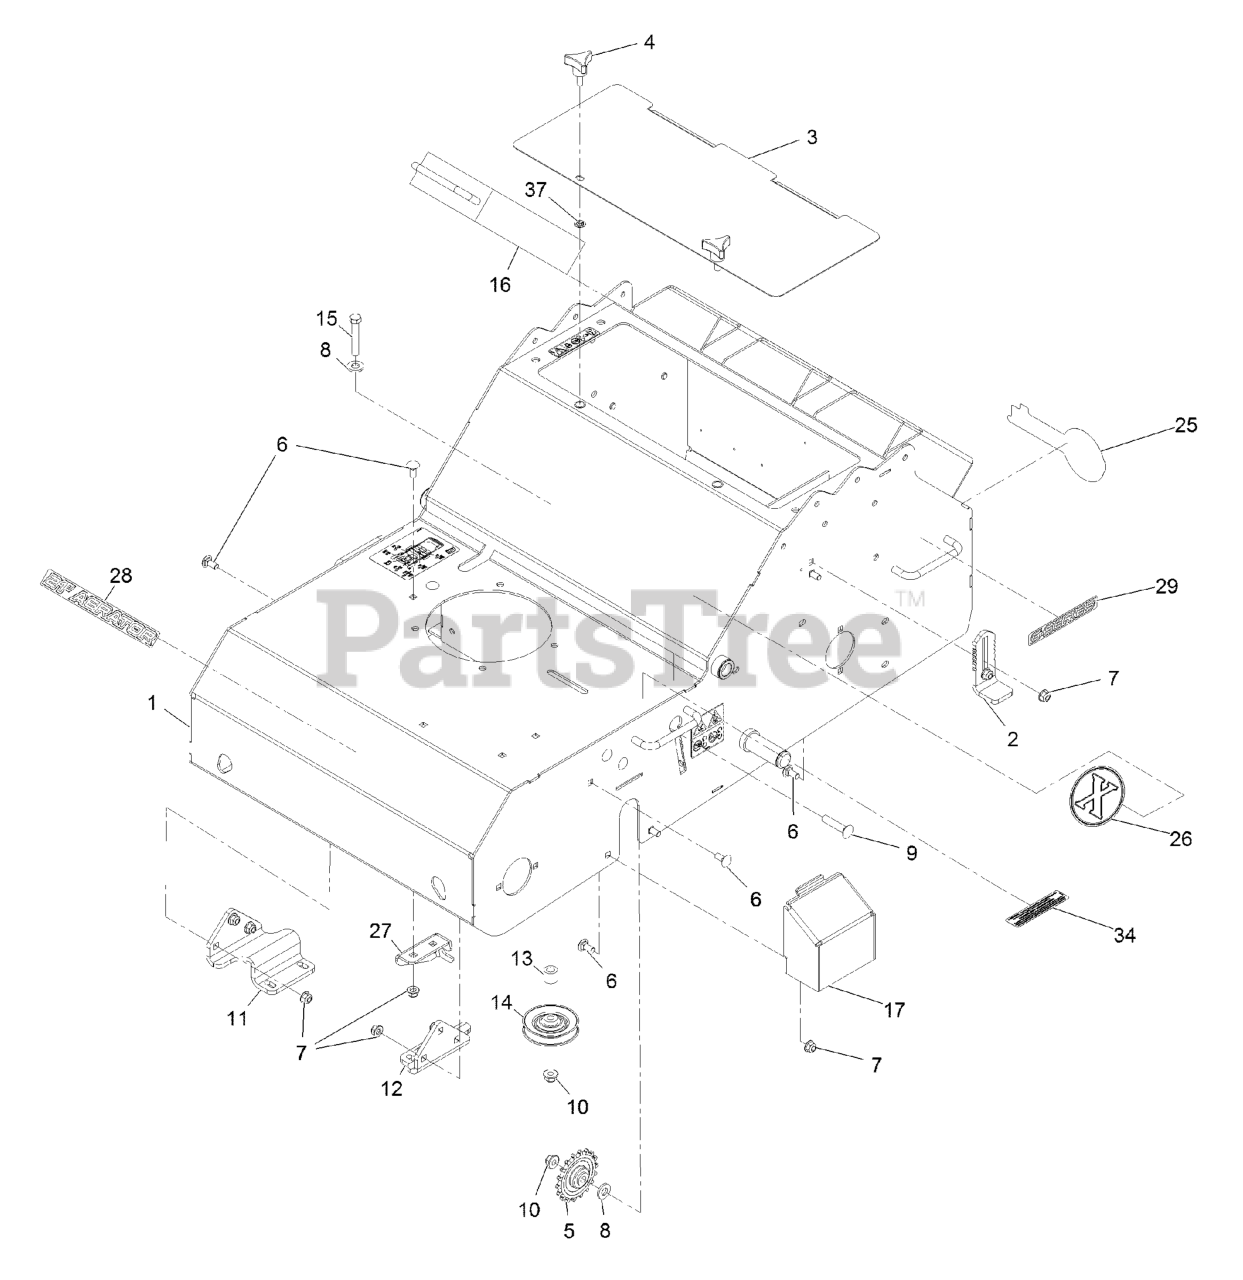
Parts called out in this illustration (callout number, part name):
1	FRAME ASM
2	STOP-DEPTH
3	COVER-ACCESS
5	SPROCKET-IDLER
6	BOLT-CARR
7	NUT-HF, NI
9	SCREW-CARR
10	NUT-HF, NI
11	BRACKET-MOUNT AXLE, RH
12	BRACKET-MOUNT AXLE, LH
13	BUSHING-IDLER
15	SCREW-HH
16	WEIGHT-AERATOR
17	COVER-TRANSAXLE
25	DECAL, EXMARK LOGO
26	Decal-X-Logo
27	BRACKET-MOUNTING, CABLE
28	DECAL-AERATOR 21 LOGO
29	Decal-S-Series
34	DECAL-ARRESTOR, SPARK
37	NUT-PUSH
